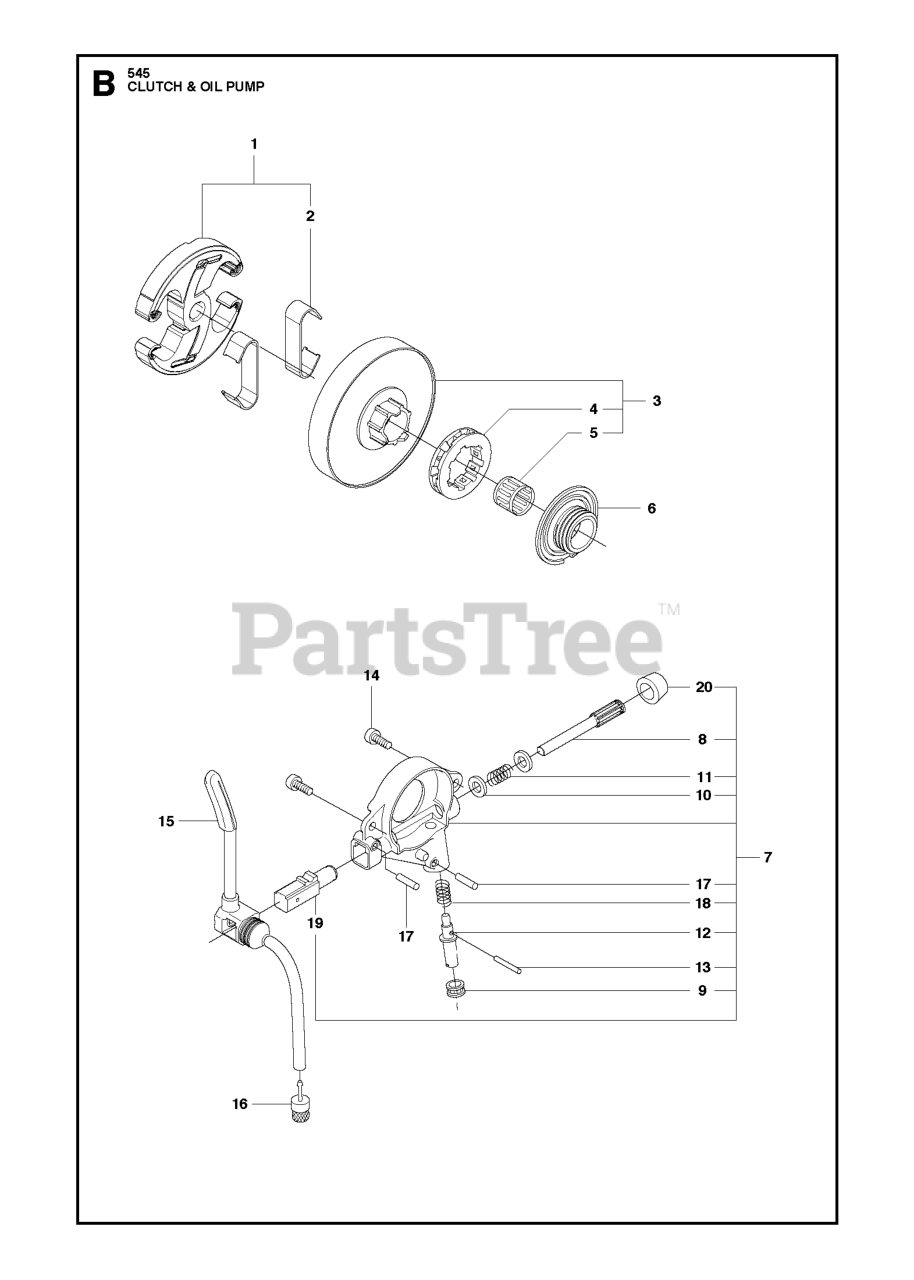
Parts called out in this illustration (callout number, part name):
3	CLUTCH DRUM ASSY RIM .325"7T
4	RIM SPROCKET 7T .325
5	SUPPORT BUSHING
6	WORM WHEEL
7	OIL PUMP ASSY
8	PUMP PISTON
12	ADJUSTING SCREW
14	SCREW ITXSCM M4X15 T27 12.9 T
16	OIL PLUMMET
19	PUMP CYLINDER
